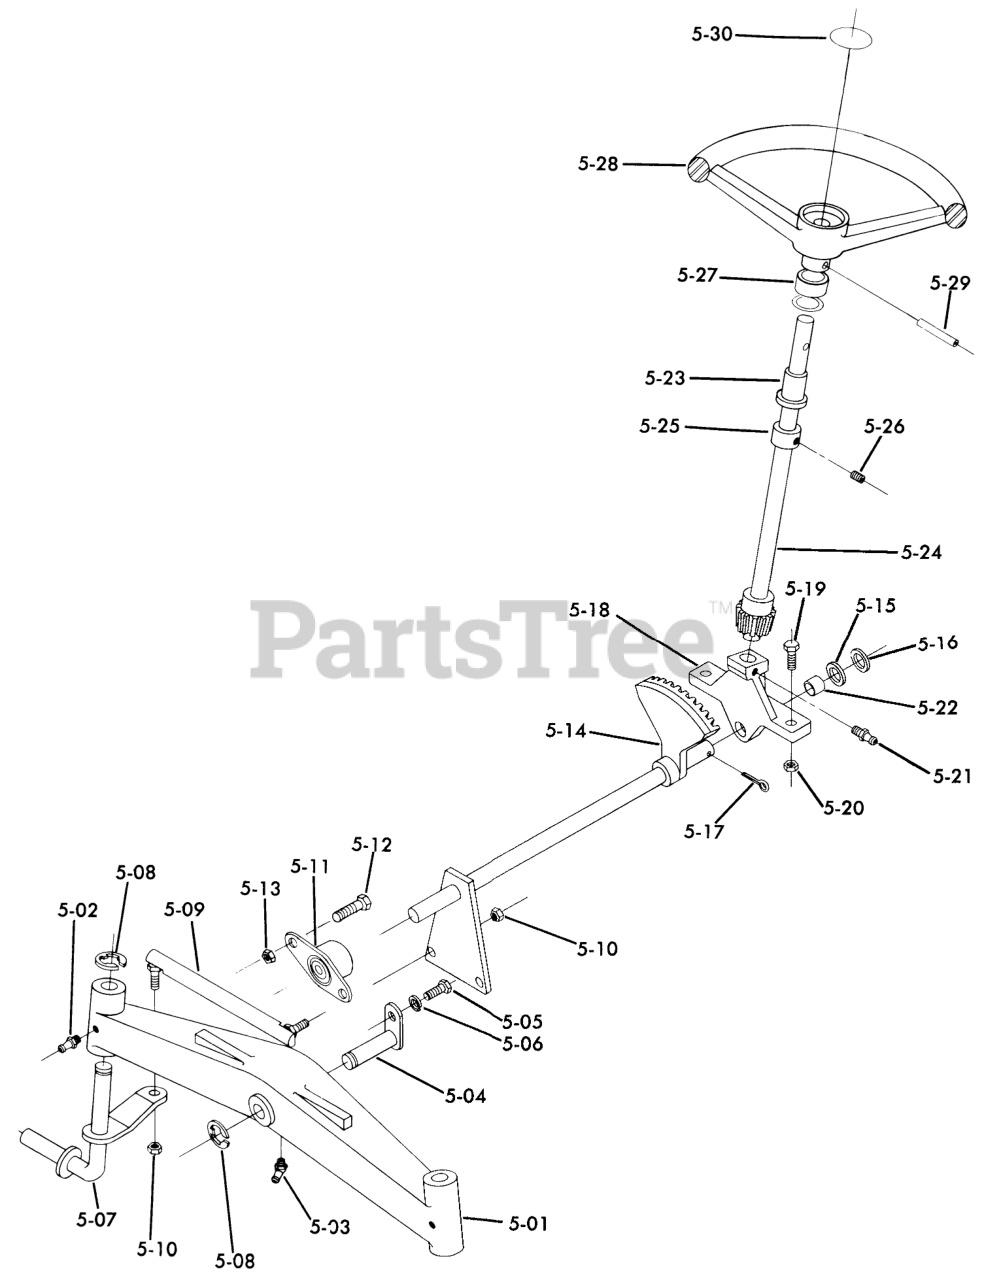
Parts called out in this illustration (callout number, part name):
5-01	AXLE-FRONT
5-02	Zerk
5-03	FITTING-GREASE
5-04	PIN AND PLATE ASM
5-05	H H C S
5-06	Lockwasher
5-07	R.H. Spindle
5-07	L.H. Spindle
5-08	E-RING
5-09	Tie Rod RH
5-09	Tie Rod LH
5-10	NUT-6
5-11	BEARING-FLANGED
5-12	BOLT
5-13	Nut
5-14	Lower Steering Shaft
5-15	WASHER-SHIM
5-16	WASHER
5-17	PIN-4
5-18	Support
5-19	Bolt
5-20	Nut
5-21	Zerk
5-22	BEARING-BRONZE
5-23	BEARING
5-24	Upper Steering Shaft
5-25	Collar
5-26	SCREW-SET
5-27	Collar
5-27	WASHER-BOWED
5-28	STEERING WH 13" SOFT
5-29	Pin-Roll
5-30	STEERING WHEEL INSE
